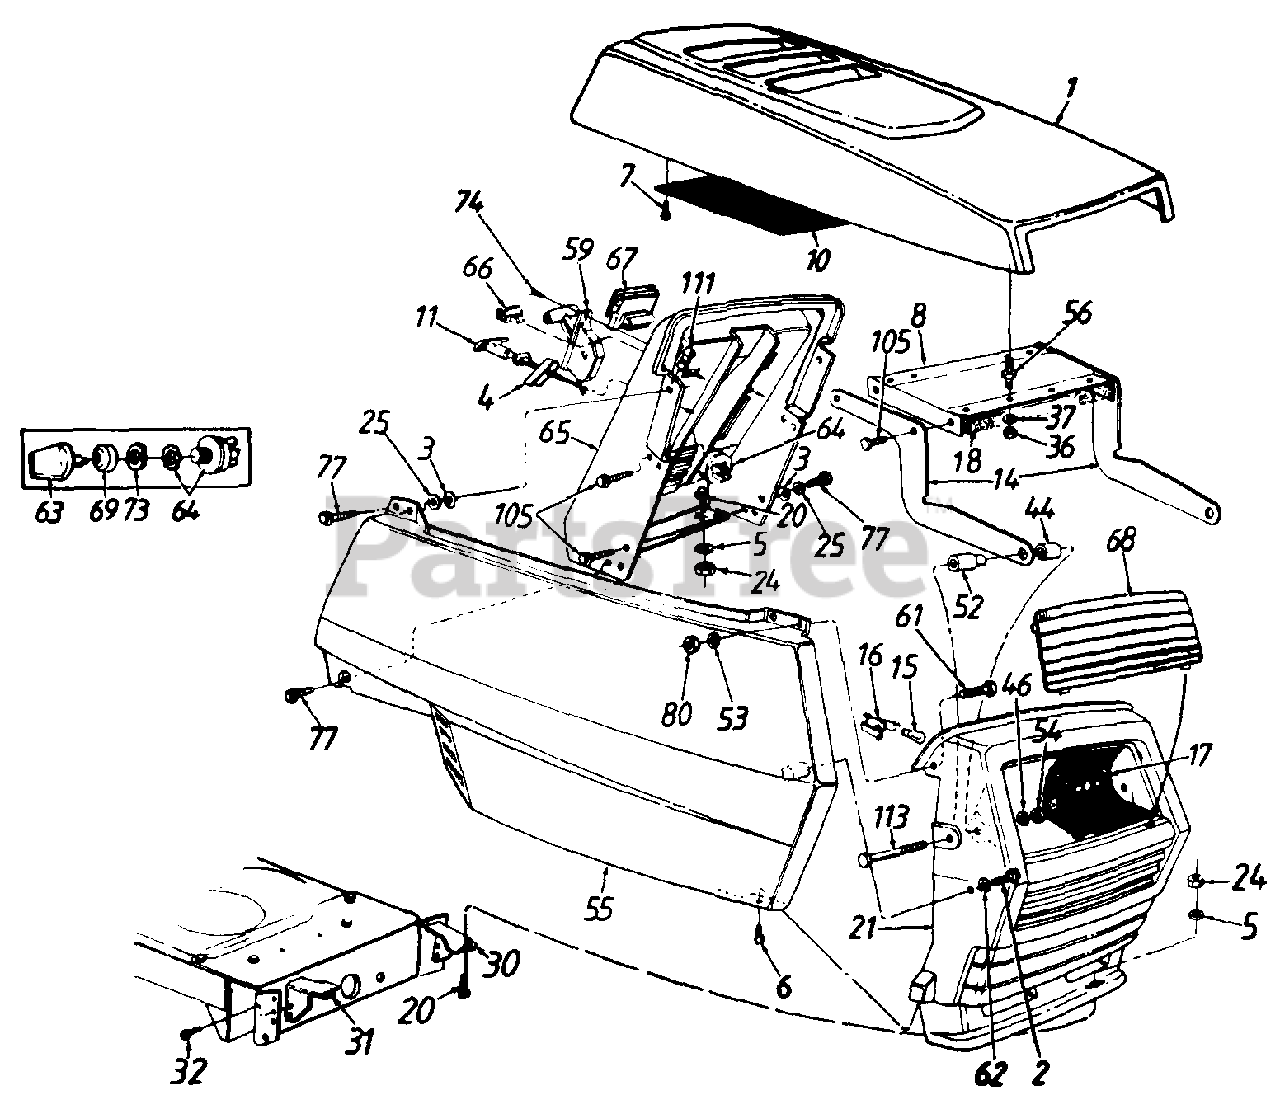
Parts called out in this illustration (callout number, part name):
3	Bolt Retainer 1/4" I.D.
4	Retainer Clip
5	Fl-Wash. .34" I.D. x .68"
6	Truss Mach. AB-Tap Scr. #10 x .5" Lg.
7	Hex Wash. Hd. AB-Tap Scr. #8 x .5" Lg.
11	Choke Control 38" Lg.
14	Hood Hinge
15	Lamp
16	Twist Lock - Lamp Socket
17	Reflector - Headlight
20	Hex Bolt 5/16-18 x .75" Lg.
21	Grille
24	Hex Nut 5/16-18 Thd.
25	Fl-Wash. 1/4" I.D. x .93" O.D.
30	Grille Mount Brk't. - L.H.
31	Grille Mount Brk't. - R.H.
32	Hex Wash. Hd. AB-Tap Scr. 5/16 x .75" Lg.
36	Hex Nut 1/4-20 Thd.
37	Bell-Wash. .265" I.D. x .75"
44	Spacer.33" I.D. x .625" O.D
46	Fl-Wash. .328" I.D. x .68" O.D.
52	Shld. Spacer .33" I.D.
53	Fl-Wash. .281" I.D. x .5" O.D.
54	Hex L-Nut 5/16-18 Thd.
55	Side Cover Ass'y. - R.H.
56	Double Ended Stud 1/4-20 Thd.
59	Throttle Control Box Ass'y.
61	Hex Bolt 1/4-20 x .62" Lg.
62	Fl-Wash. .281" I.D. x .73" O.D.
64	Ignition Switch
65	Dash Panel
66	Light Switch
67	Ammeter
68	Lens
69	Ignition Switch Cap
73	Ignition Switch Nut
74	Truss Mach. AB-Tap Scr. #10 x .5" Lg.
77	Hex Wash. Hd. Tap Scr. 1/4 x .75" Lg.
80	Hex L-Nut 1/4-20 Thd.
105	Hex Tap Scr. 1/4-20 x .5" Lg.
111	Speed Nut 1/4-20 Thd.
113	Hex Bolt 5/16-18 x 2.75"
